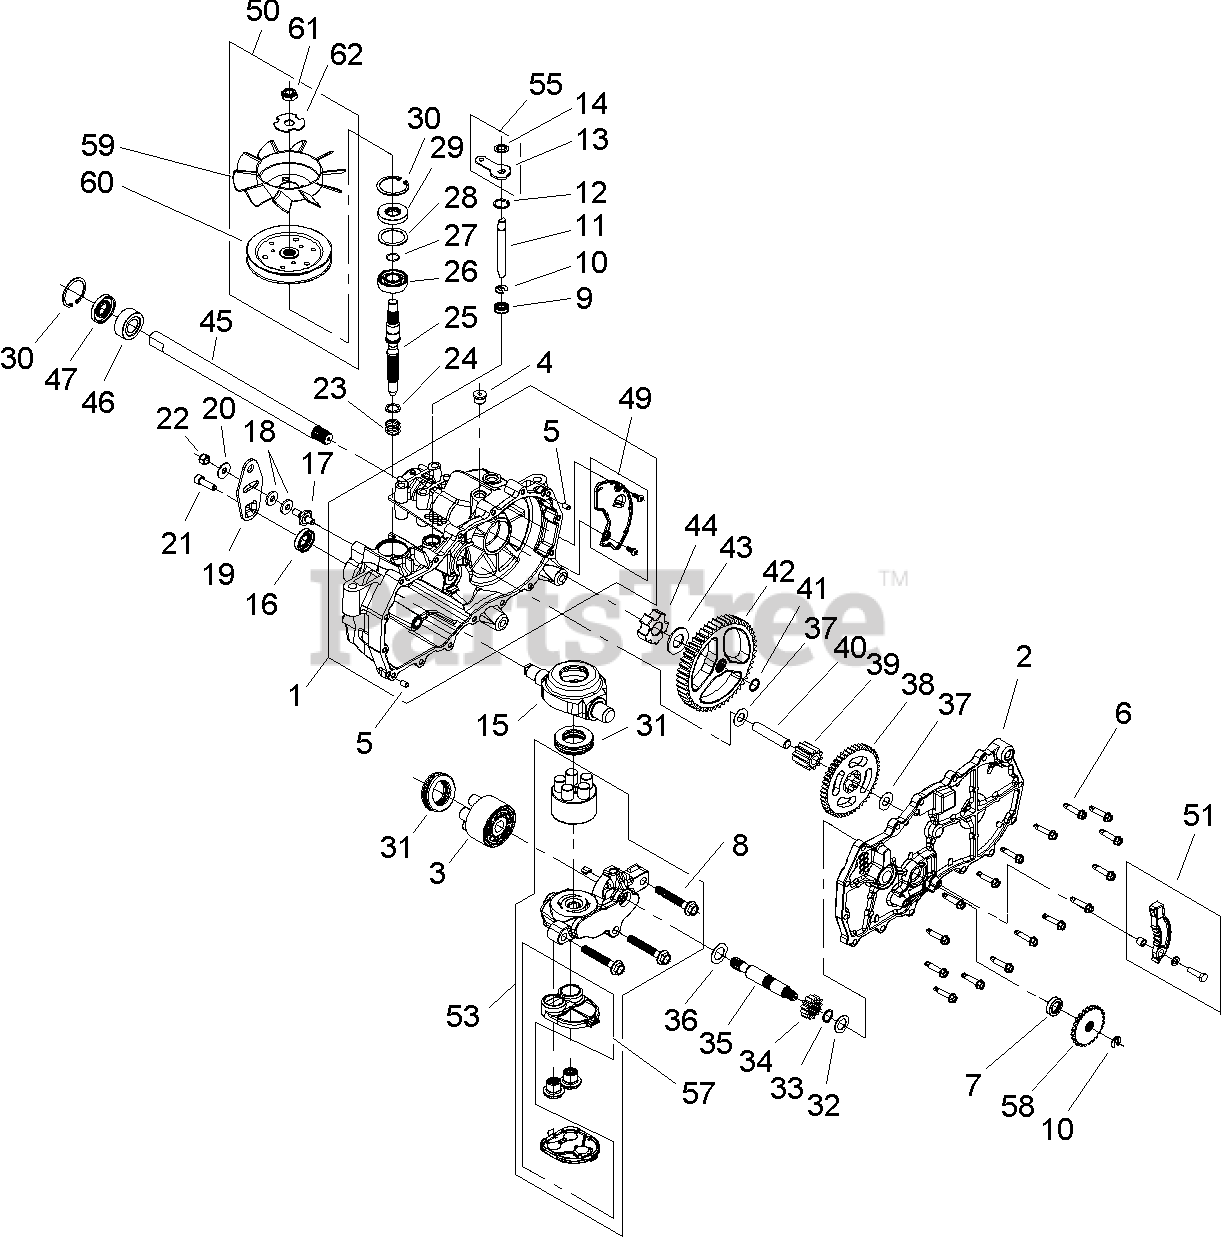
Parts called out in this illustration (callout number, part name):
1	RH Main Housing ASM
2	RH Side ASM
3	CYLINDER BLOCK KIT
4	PLUG-THREAD, STRAIGHT
6	SCREW-HHF
9	SEAL-LIP
10	RING-RETAINING, EXT
11	ROD-BYPASS
12	RING-RETAINING, INT
13	ARM-BYPASS
14	RING-RETAINING, EXT
15	SWASHPLATE-TRUNNION
18	PUCK-FRICTION
19	ARM-CONTROL
20	WASHER-PIVOT
23	SPRING-BLOCK
24	WASHER-BLOCK, THRUST
25	SHAFT-INPUT
26	BEARING-BALL
27	RING-RETAINING
30	RING-RETAINING
31	BEARING-THRUST
32	WASHER-FLAT
33	RING-RETAINING
34	GEAR-PINNION, 13T
35	SHAFT-MOTOR
36	WASHER-SHAFT, MOTOR
39	GEAR-JACKSHAFT, 10T
40	PIN-JACKSHAFT
41	RING-RETAINING, SPIRAL
42	GEAR-BULL, 52T
44	BEARING-SLEEVE
45	AXLE
46	BEARING-SLEEVE, OUTBOARD
49	RH Expansion Plate Kit
50	Fan Pulley Kit
51	BRAKE ARM KIT
53	RH 7-PISTON CENTER SECTION KIT
55	BYPASS ARM KIT
57	FILTER KIT
58	DISC-BRAKE, COG
59	FAN-6 INCH, 10 BLADE
62	WASHER-SLOTTED
